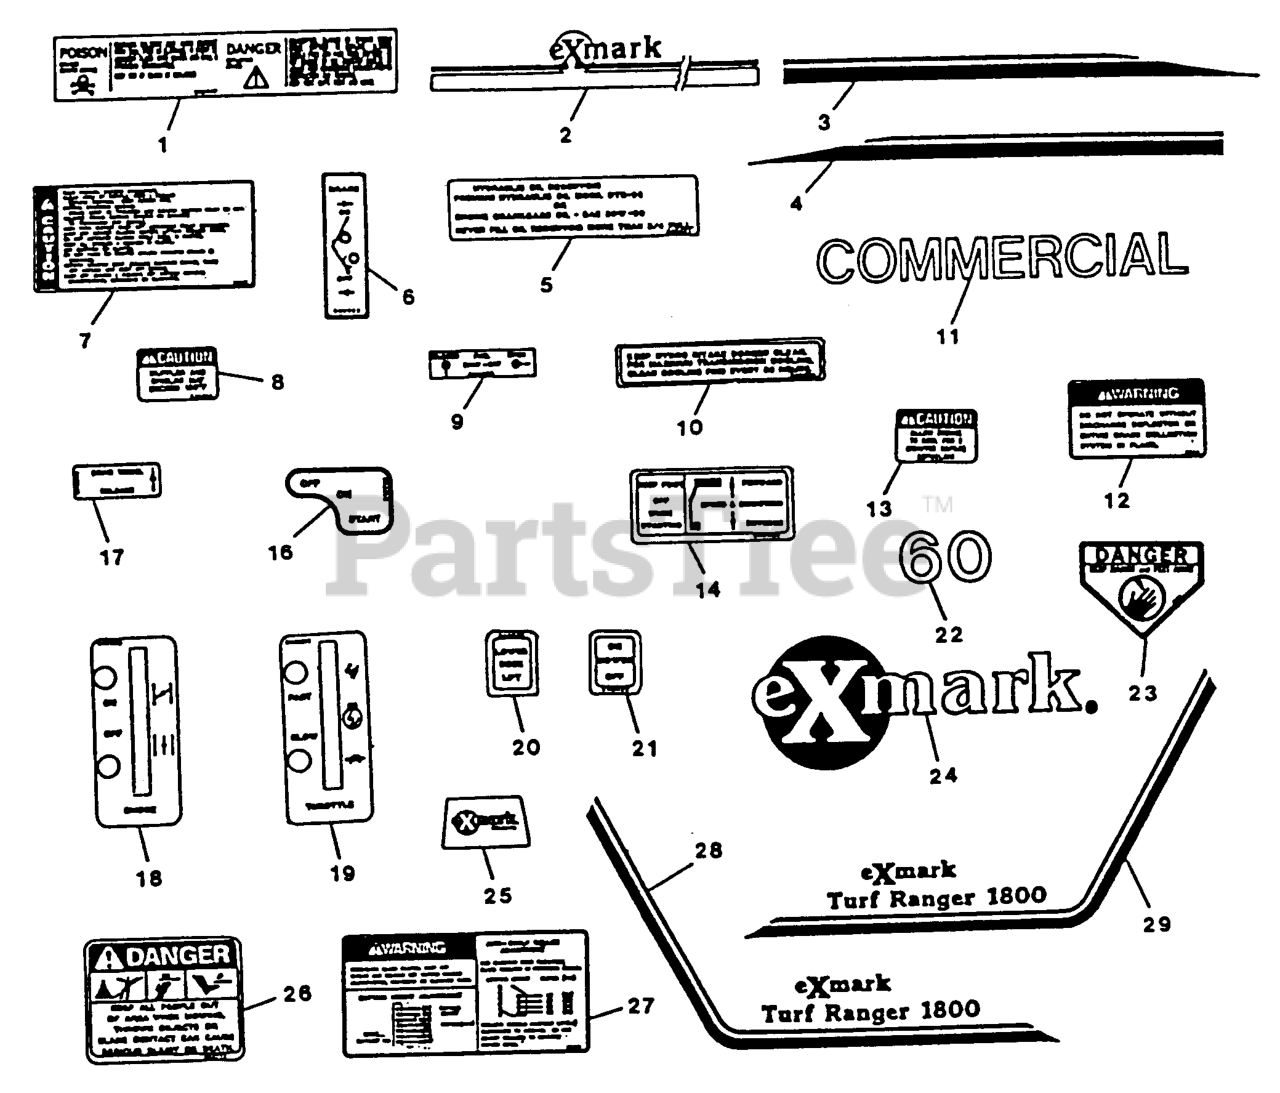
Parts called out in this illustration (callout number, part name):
1	DECAL-BATTERY
10	DECAL,INTAKE
14	DECAL,FOOT PEDAL
20	DECAL-DECK LIFT
21	DECAL-MOWER SWITCH
23	DECAL-DANGER
26	DECAL-DANGER
